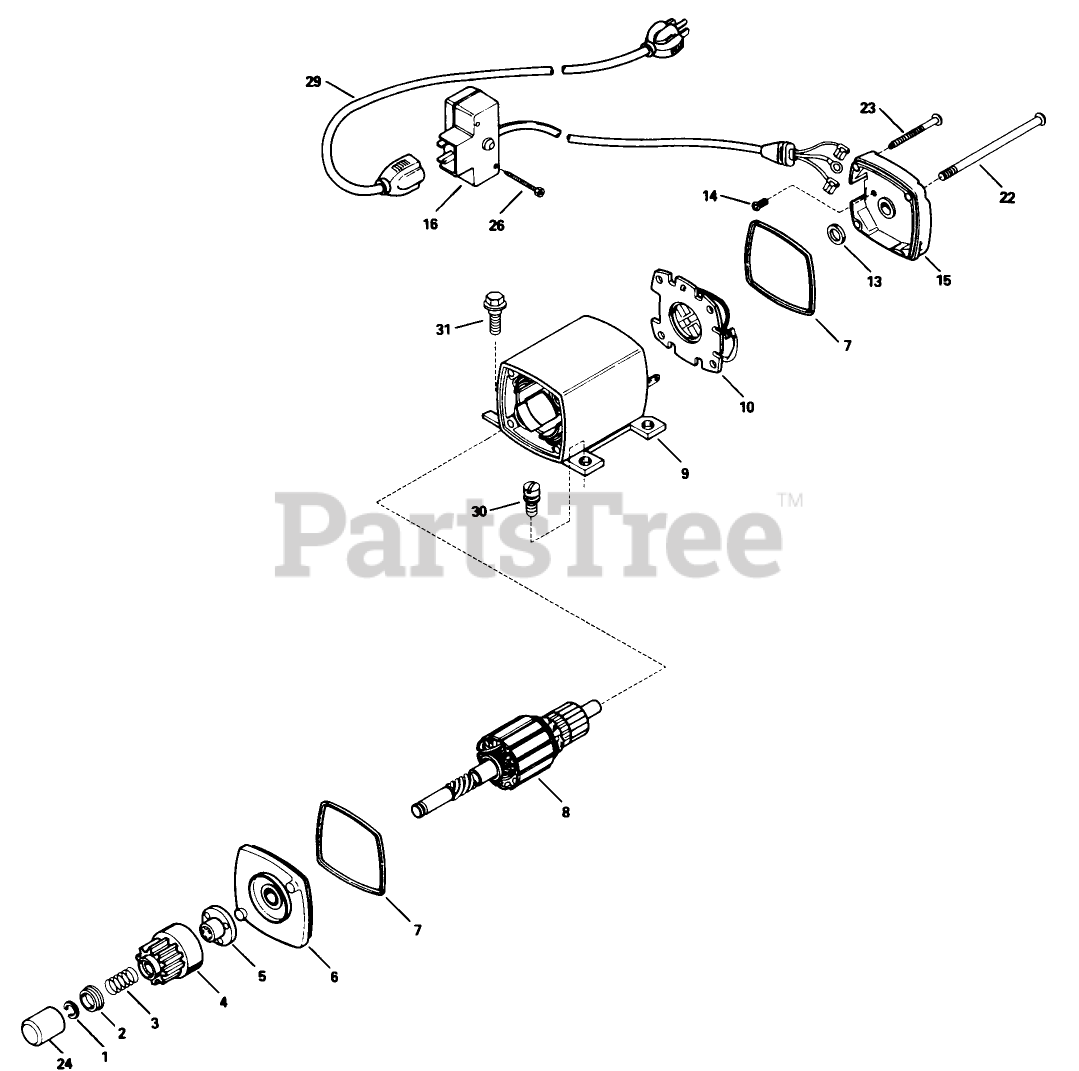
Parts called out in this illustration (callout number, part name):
1	Ring-Retainer
2	Retainer-Spring
3	Spring-Anti Drift
4	Gear
5	Nut-Engaging
6	Cap Assembly-Cap End (Incl. Ref. #7)
7	O-Ring
8	Armature
9	Housing Assy.
10	Card ASM
13	Washer-Thrust
14	Screw-Ground
15	Cap Assembly (Incl. Ref. #7)
16	Box Assembly-Switch (Incl. Ref. #26)
22	Bolt-Case
23	Screw-Ground
24	Cover-Dust
26	Screw
29	Cord-Extension
30	Screw
31	Screw (1/4-20x1/2)
